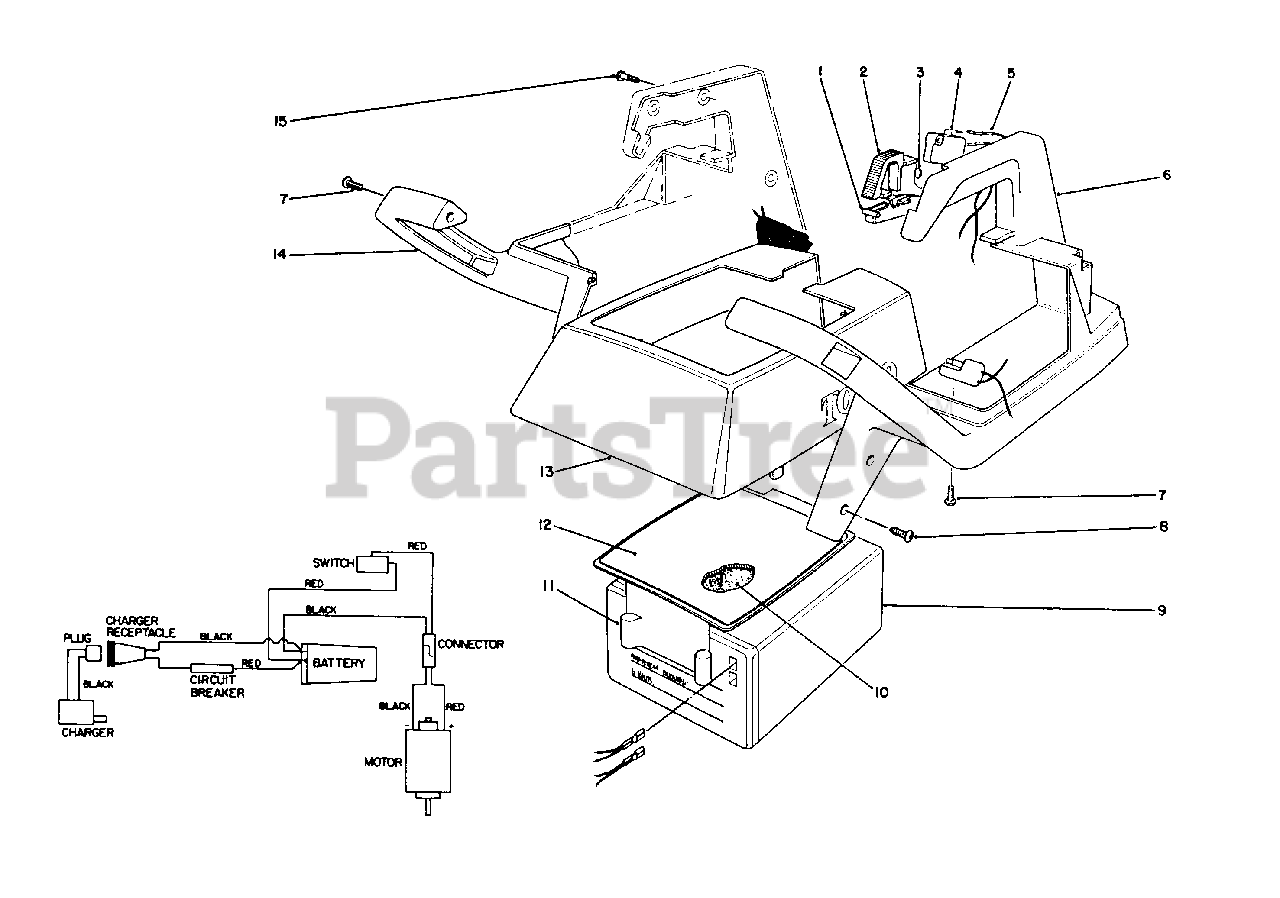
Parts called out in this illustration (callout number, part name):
2	Trigger Release
5	Wiring Harness
6	Left Handle & Battery Case
7	Screw
8	Self Tapping Screw
10	Foam Pad
11	Panel-Control
12	Decal-Control Panel
13	Cover
14	Right Hand & Battery Case
